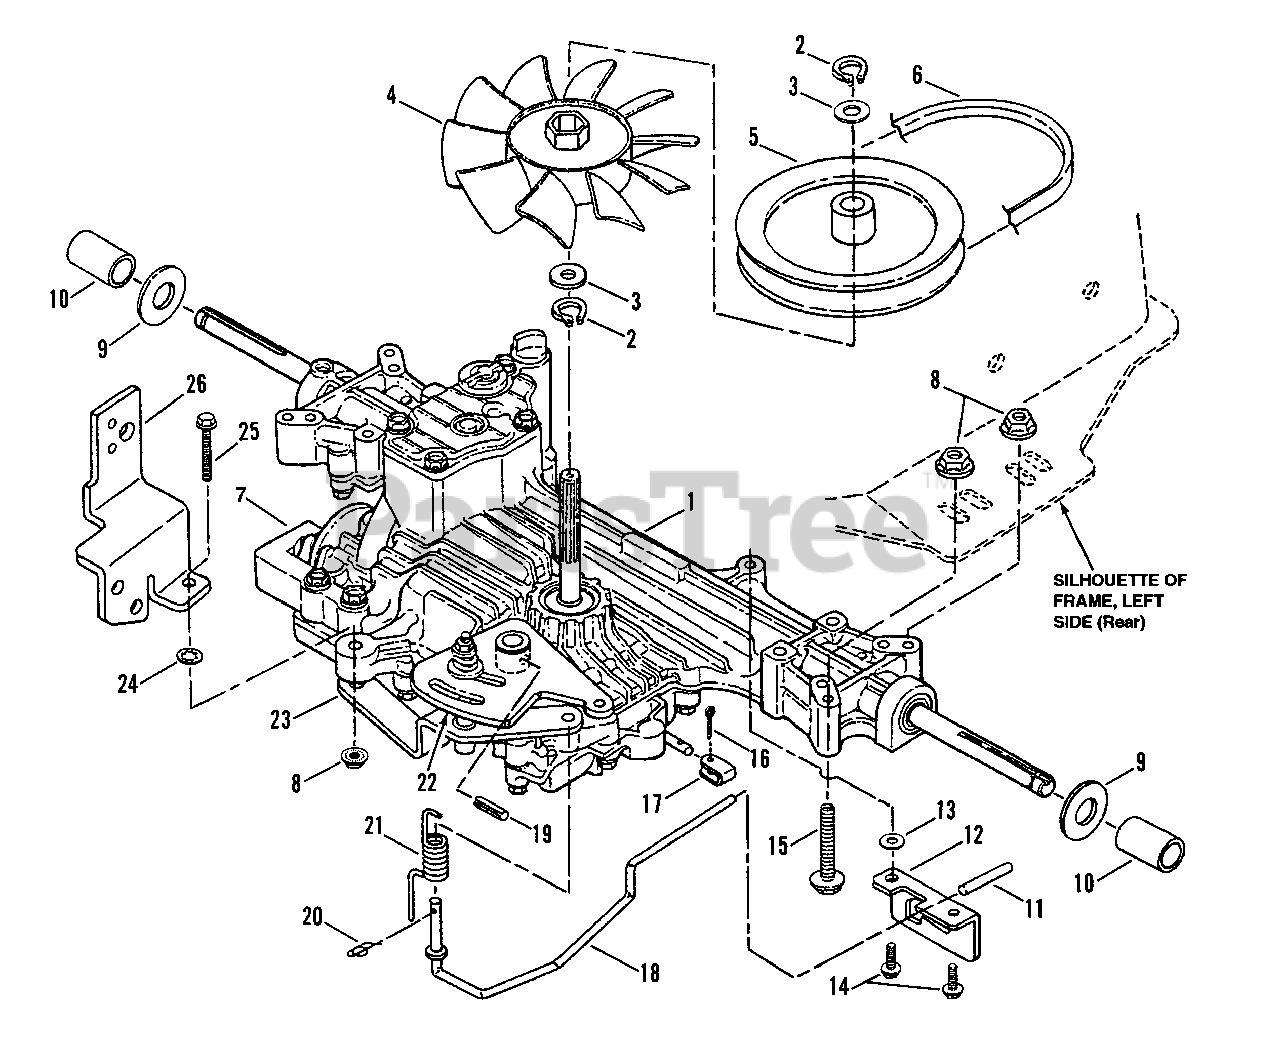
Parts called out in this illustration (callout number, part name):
1	TRANSAXLE ASSEMBLY
2	RING, Retaining
3	WASHER, Fan/Hub
4	FAN
5	PULLEY, Drive
6	BELT, Traction Drive
8	NUT, 5/16-18 Hx. Flg. Lk.
9	WASHER, Flat
11	GRIP, Roll Release
12	DETENT, Roll Release
13	WASHER, 3/4" O.D. Flat
14	SCREW, 3/8-16 x 1 1/4" Self-Tapping
15	BOLT, 5/16-18 x 2 1/4" Hex Flange Lock
16	COTTER-PIN, 5/32 x 1"
17	LINK, Roll Release
18	WIREFORM, Roll Release
19	ROLL-PIN, Speed Control Arm
20	COTTER-PIN, 5/16 Self-Locking
21	SPRING, Torsion, Roll Release
22	ASSEMBLY, Speed Control/Friction
22	WELDMENT, Speed Control Arm
22	SPRING
22	STUD, Friction
22	NUT, 3/8-16 Hex Flange Lock
22	WASHER, 13/32" I.D. x 1 1/2" O.D.
22	WASHER, Friction Pad
23	SUPPORT, Friction Stud Assembly
23	BUSHING, Flange
23	SUPPORT, Friction Stud
24	RETAINER, 5/16 Bolt
25	BOLT, 5/16-18 x 2" Hex Flange Lock
26	BRACKET, Spool
